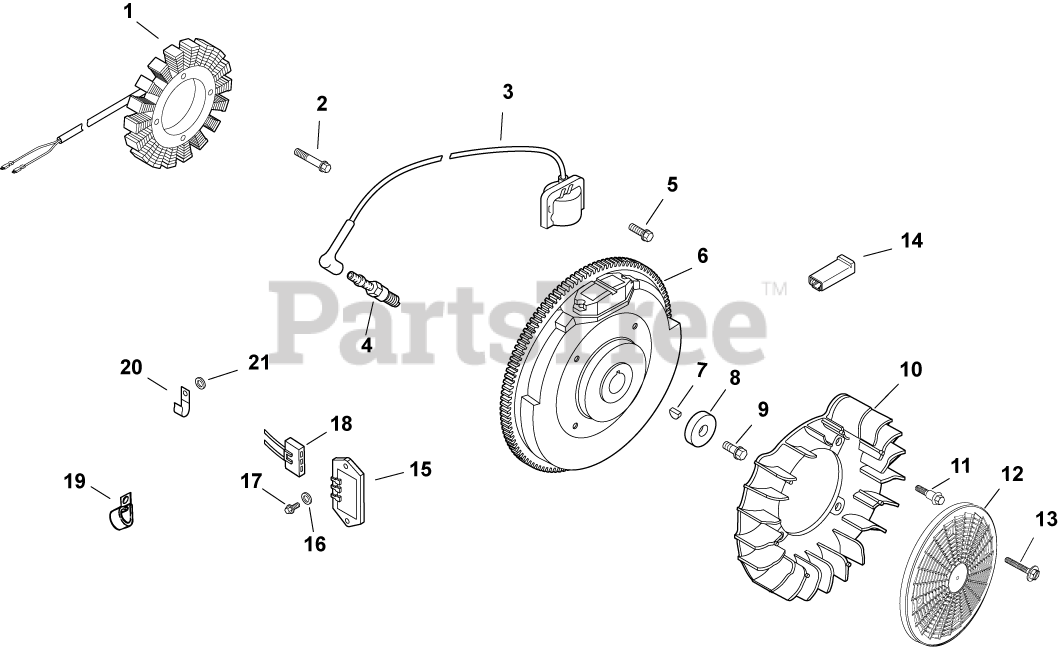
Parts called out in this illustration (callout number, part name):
1	KIT, 25 AMP STATOR ASSY.
2	SCREW, THD FROM M5X0.8X30
3	KIT, MODULE IGNTN (CDI FIXED)
4	PLUG, SPARK (PRO SERIES)
5	SCREW, FLG THD FRM M5X.8X20-(#25086399S)
6	FLYWHEEL, PAINTED-USE 24 025 59-S
7	KEY, 3/16" X 5/8"
8	WASHER, FLAT 13/32"
9	SCREW, FLG M10X1.5X45 - (#25086361S)
10	FAN USE 24 755 253-S
11	BOLT, SHOULDER
12	SCREEN, GRASS-USE 24 162 45-S
13	SCREW, FLG SEMS M4X.7X25
14	CONNECTOR (1 CONTACT)
15	REG/RECTIFIER (20/25 AMP)-USE 25 403 20-
16	WASHER, FLAT 1/4" (O.D. 1/2")
17	SCREW, PHL HD #11-16X7/8"
18	CONNECTOR, BODY (KM)-USE 25 155 41-S
19	CLIP, TUBE & WIRING (KM)
20	CLIP, CABLE
21	WASHER, FLAT 7/32"
2417641-S	LEAD, DUPLEX
2417666-S	HARNESS, WIRING
24126137-S	BRACKET, GROUND STRAP USE 24 518 12-S
